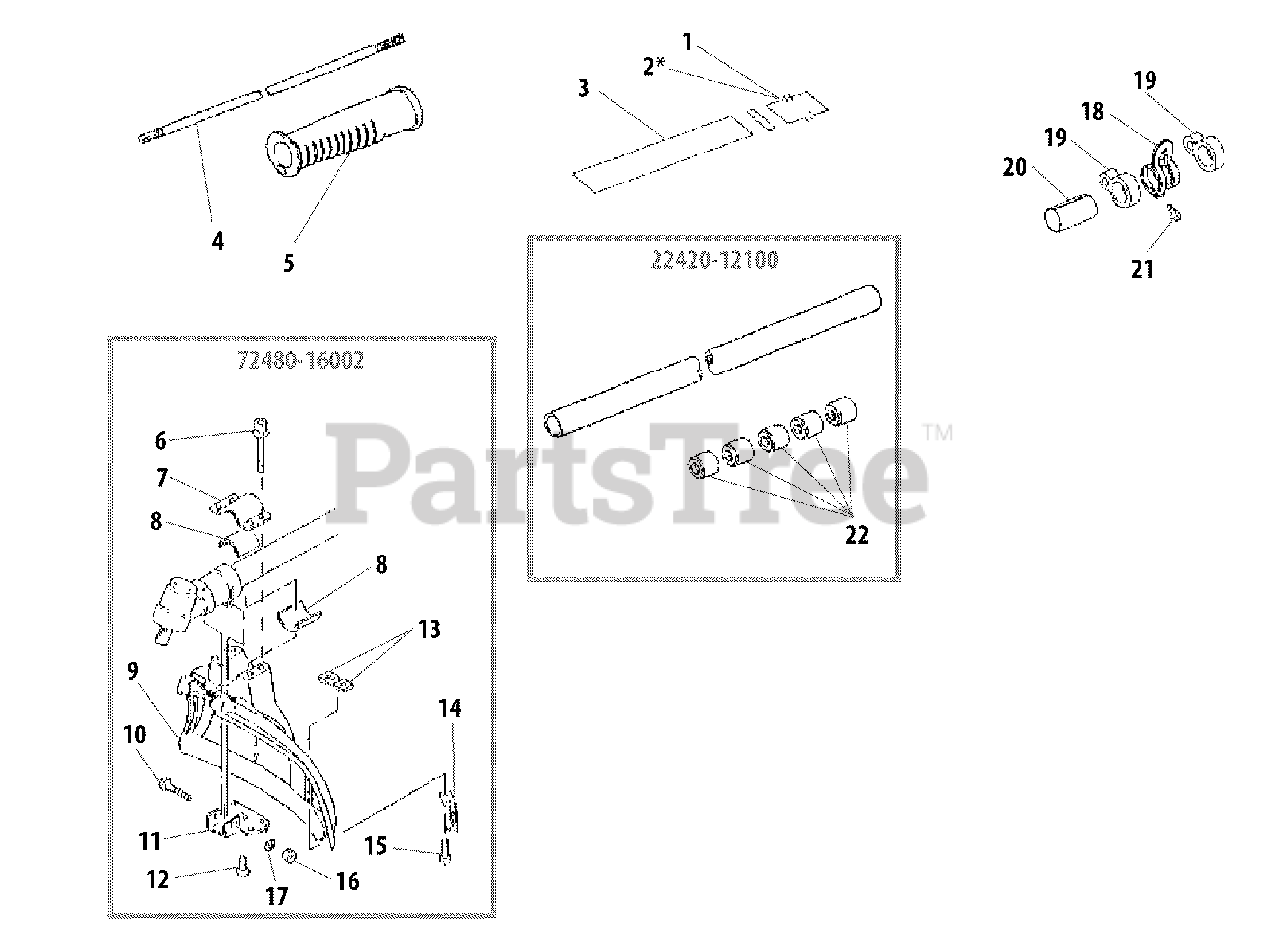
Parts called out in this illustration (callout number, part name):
1	LABEL - MODEL
2	LABEL
3	LABEL, CAUTION
4	MAINSHAFT
5	GRIP, REAR
6	BOLT M5×45
7	CLAMP, UPPER
8	SPACER
9	SHIELD, DEBRIS
10	BOLT M5×35
11	PLATE, SHIELD MOUNTING
12	SCREW HILO 4×10
13	NUT M5
14	CUTTER
15	BOLT M5×16
16	NUT M5
17	WASHER 5 MM
18	HANGER
19	GUIDE
20	SPACER
21	BOLT 5×12
22	BUSHING
A	GUARD ASSY
A	MAIN PIPE ASSY
